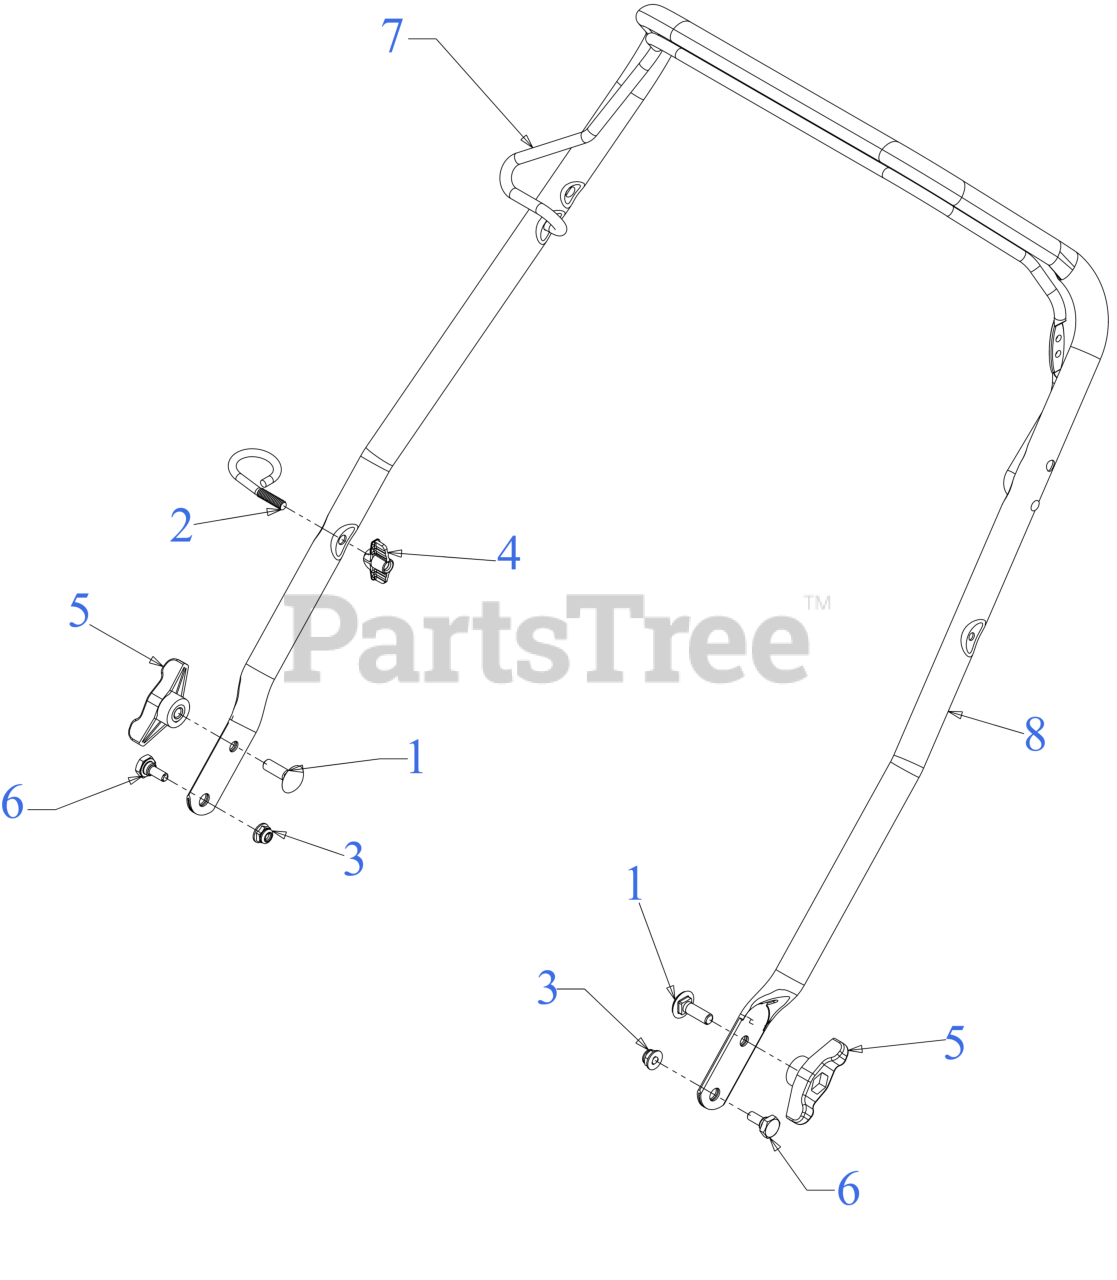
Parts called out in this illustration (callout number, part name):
1	SCREW 5/16-18 x 1.00 GR5
2	EYEBOLT 1/4-20
3	FLANGE LOCK NUT
4	HANDLE KNOB
5	WING KNOB 5/16-18
6	SHOULDER SCREW
8	UPPER HANDLE
